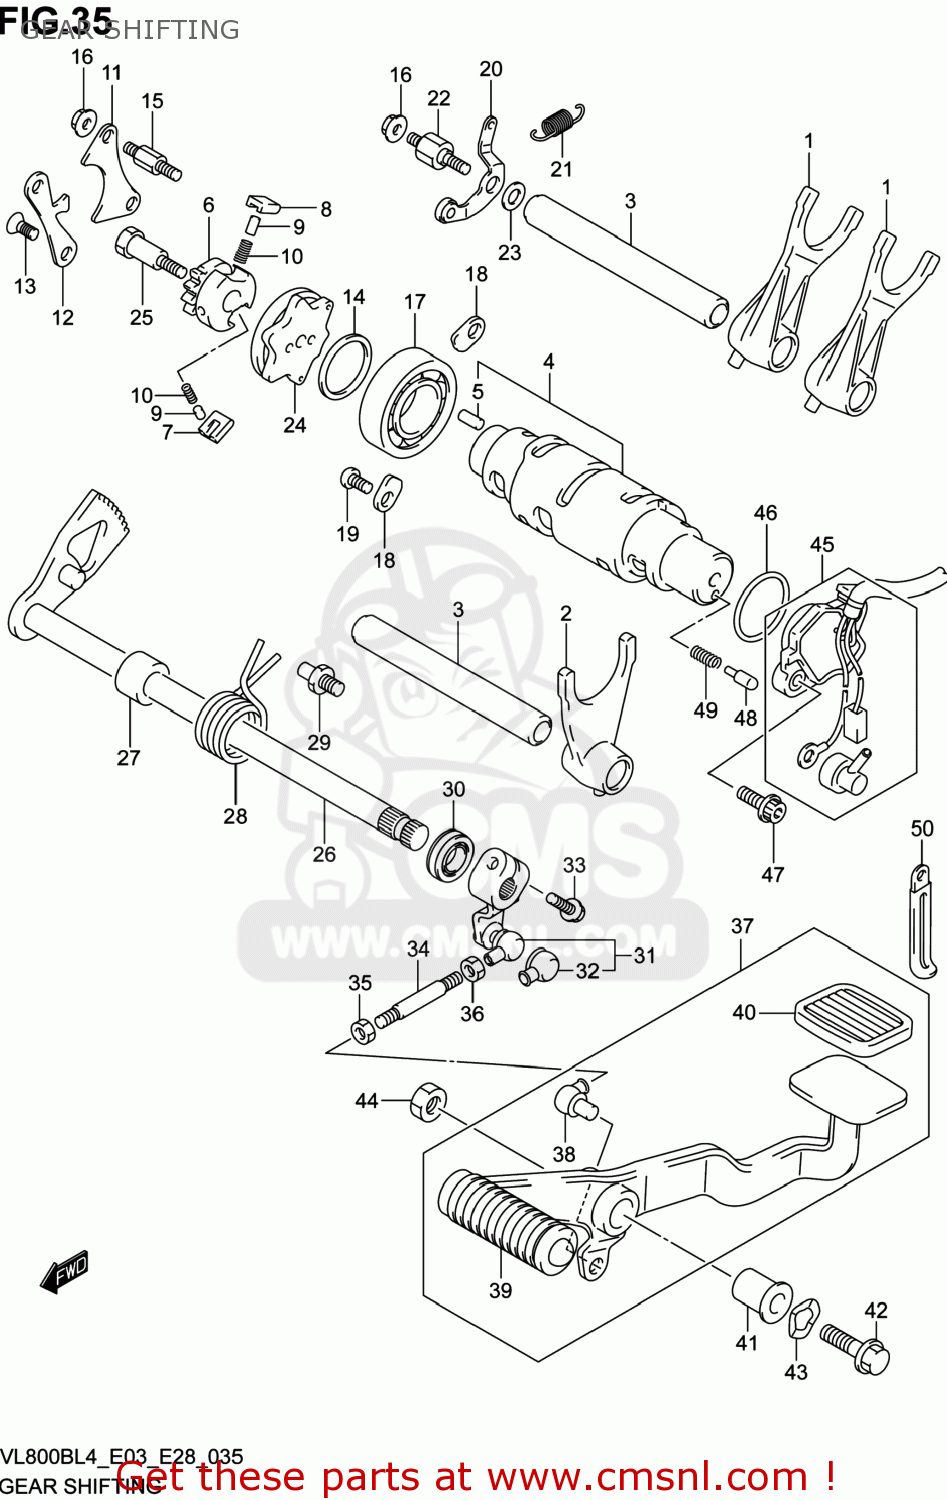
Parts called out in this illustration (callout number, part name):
1	FORK,GEAR SHIFT NO.1
2	FORK,GEAR SHIFT NO.2
3	SHAFT,GEAR SHIFT FORK(L:115)
4	CAM,GEAR SHIFT
5	PIN
6	GEAR,GEAR SHIFT CAM DRIVEN
7	PAWL,GEAR SHIFT NO.1
8	PAWL,GEAR SHIFT NO.2
9	PIN(5X8)
10	SPRING
11	LIFTER,GEAR SHIFT POLE
12	GUIDE,GEAR SHIFT CAM
13	SCREW(6X12)
14	WASHER(25X32X3)
15	BOSS,SHIFT POLE LIFTER
16	NUT
17	BEARING(25X47X8)
18	RETAINER
19	SCREW(6X12)
20	STOPPER,GEAR SHIFT CAM
21	SPRING
22	SUPPORT,CAM STOPPER ARM
23	WASHER
24	PLATE,GEAR SHIFT CAM
25	PIN,SHIFT CAM DRIVEN GEAR
26	SHAFT,GEAR SHIFT
27	SPACER(12X20X15.3)
28	SPRING
29	STOPPER,GEAR SHIFT ARM
30	SEAL,OIL (12X22X9)
31	ARM,GEAR SHIFT LINK
32	COVER,DUST
33	BOLT
34	ROD,GEAR SHIFT LINK
35	NUT
36	NUT
37	LEVER ASSY,GEAR SHIFT
38	COVER,DUST
39	RUBBER
40	RUBBER,BRAKE PEDAL
41	SPACER,GEAR SHIFT LEVER
42	BOLT(10X40)
43	WASHER
44	NUT
45	BASE ASSY,GEAR SHIFT TERMINAL
46	O RING(D:2.4,ID:26.2)
47	BOLT
48	PIN(5X15.5)
49	SPRING
50	CLAMP(L:80)
